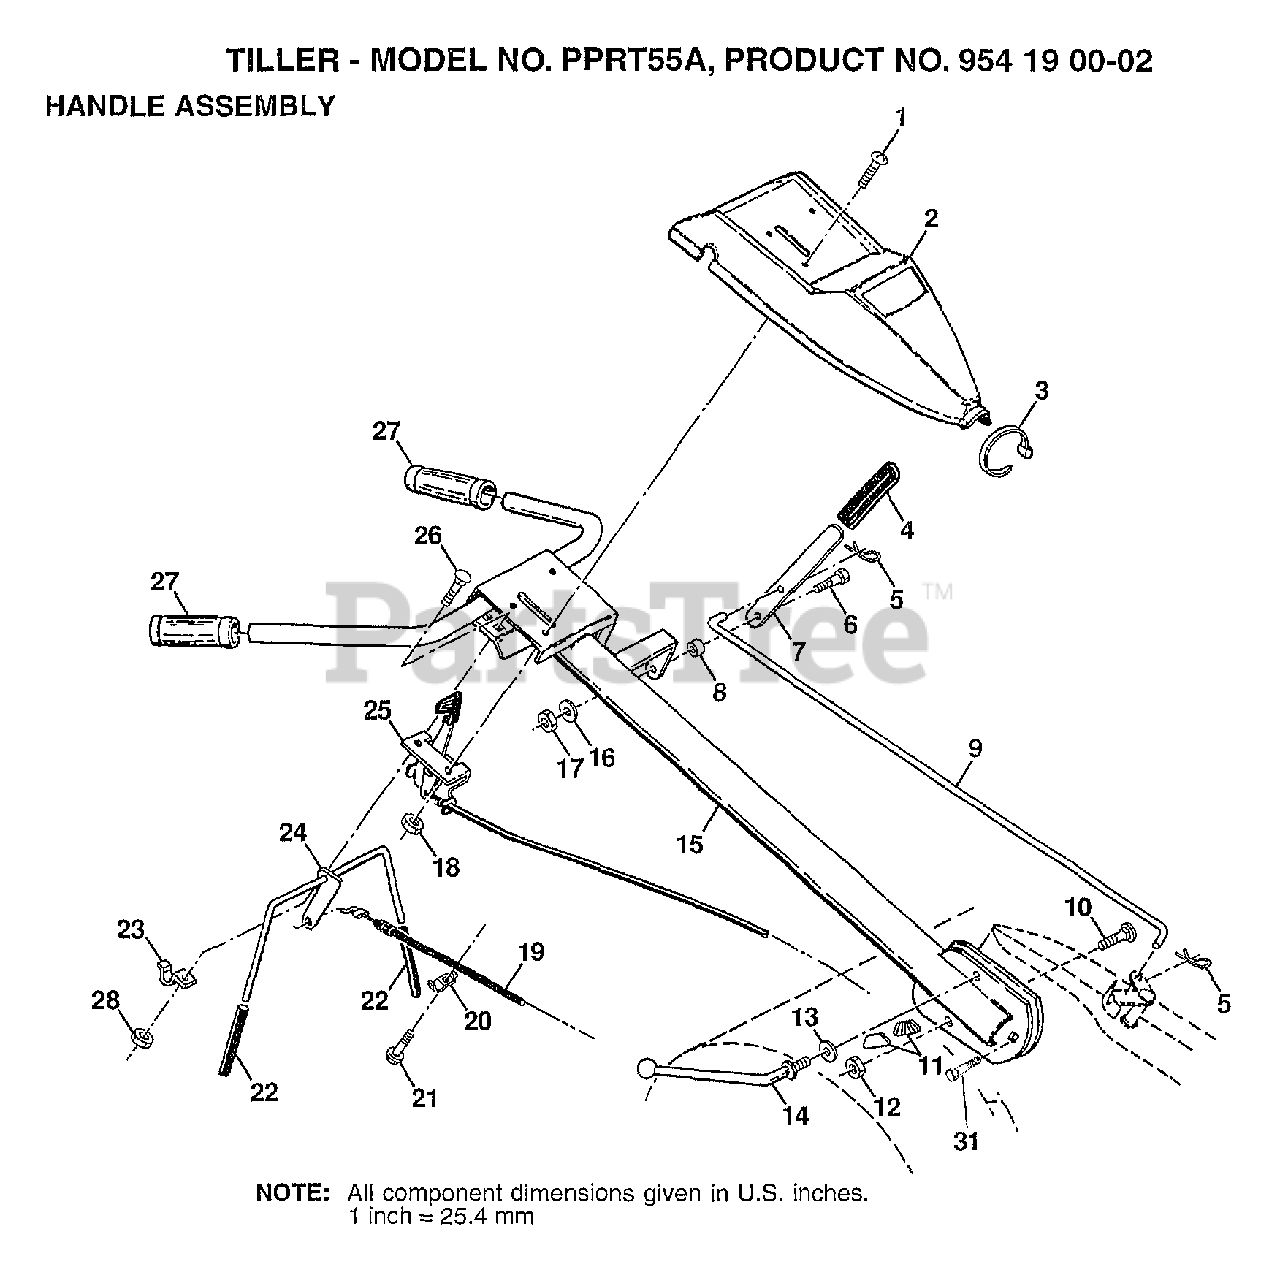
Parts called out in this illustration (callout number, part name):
1	SCREW.PNHD.10-24
2	PANEL, CONTROL
6	SHOULDER BOLT ST
8	GROMMET, RUBBER
10	BOLT D
11	LOCK, HANDLE
12	LOCKNUT
13	WASHER CRT
14	LEVER, LOCK HANDLE
16	LOCKWASHER
19	CABLE.CLUTCH.48.Z
20	CONDIUT CLIP T
22	GRIP BAR CONTROL
23	CLAMP BAR CONTROL
24	BAR ASSEMBLY CONTROL
25	CONTROL THROTTLE
26	BOLT
28	NUT
31	BOLT PIVOT
